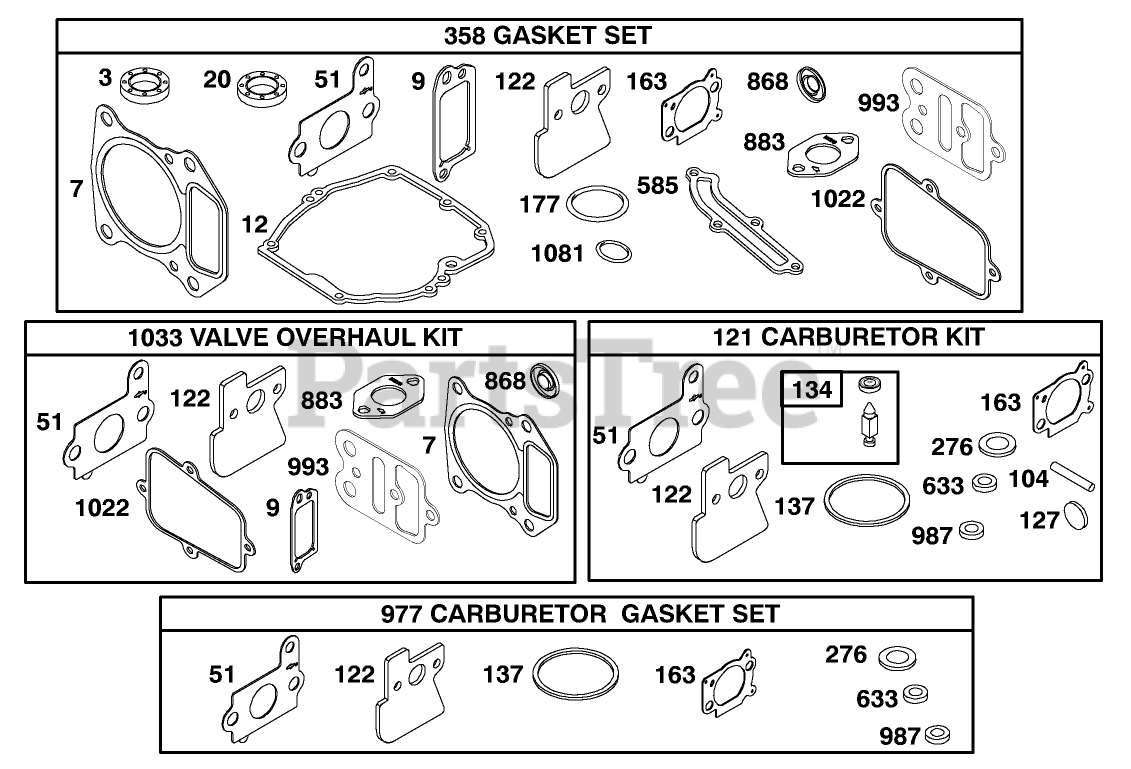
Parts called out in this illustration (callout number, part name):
3	Seal-Oil
7	Cylinder Head Gasket
9	Gasket?Breather
12	Gasket
20	Seal-Oil
51	Intake Gasket
104	Spring
121	Carburetor Overhaul Kit
122	Gasket-Intake
127	Welch Plug (Sold in Kit Only)
134	Valve-Inlet (Includes Seat)
137	Float Bowl Gasket (Sold in Kit Only)
163	Air Cleaner Gasket
177	O-Ring Seal
276	Washer(Sold in Kit Only)
358	Gasket Set
585	Gasket-Breather
708	Choke Shaft Seal (Sold in Kit Only)
868	Valve Seal
883	Exhaust Gasket
977	Gasket Set?Carburetor
987	Throttle Shaft Seal (Sold in Kit Only)
993	Gasket
1022	Rocker Cover Gasket
1033	Valve Overhaul Kit
1081	O-Ring Seal
